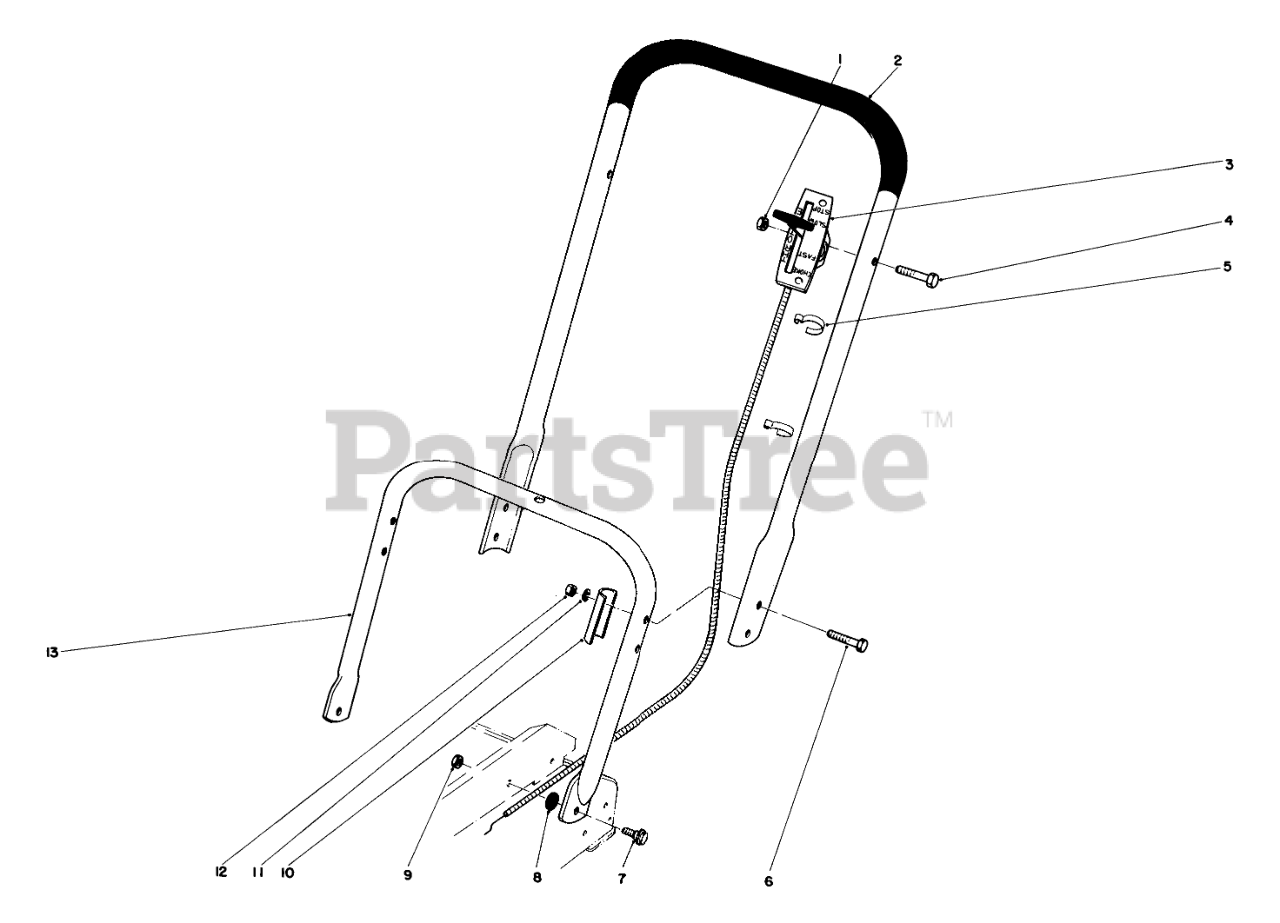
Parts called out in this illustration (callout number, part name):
1	NUT-LOCK, CONE
2	Upper Handle
3	Throttle Control
4	SCREW-HH
6	SCREW-HH
7	SCREW-SHOULDER
8	HANDLE LATCH SPACER
9	NUT-LOCK, CONE
10	Brace-Handle
11	WASHER-LOCK/SP
12	NUT-HEX
13	Handle-Lower
